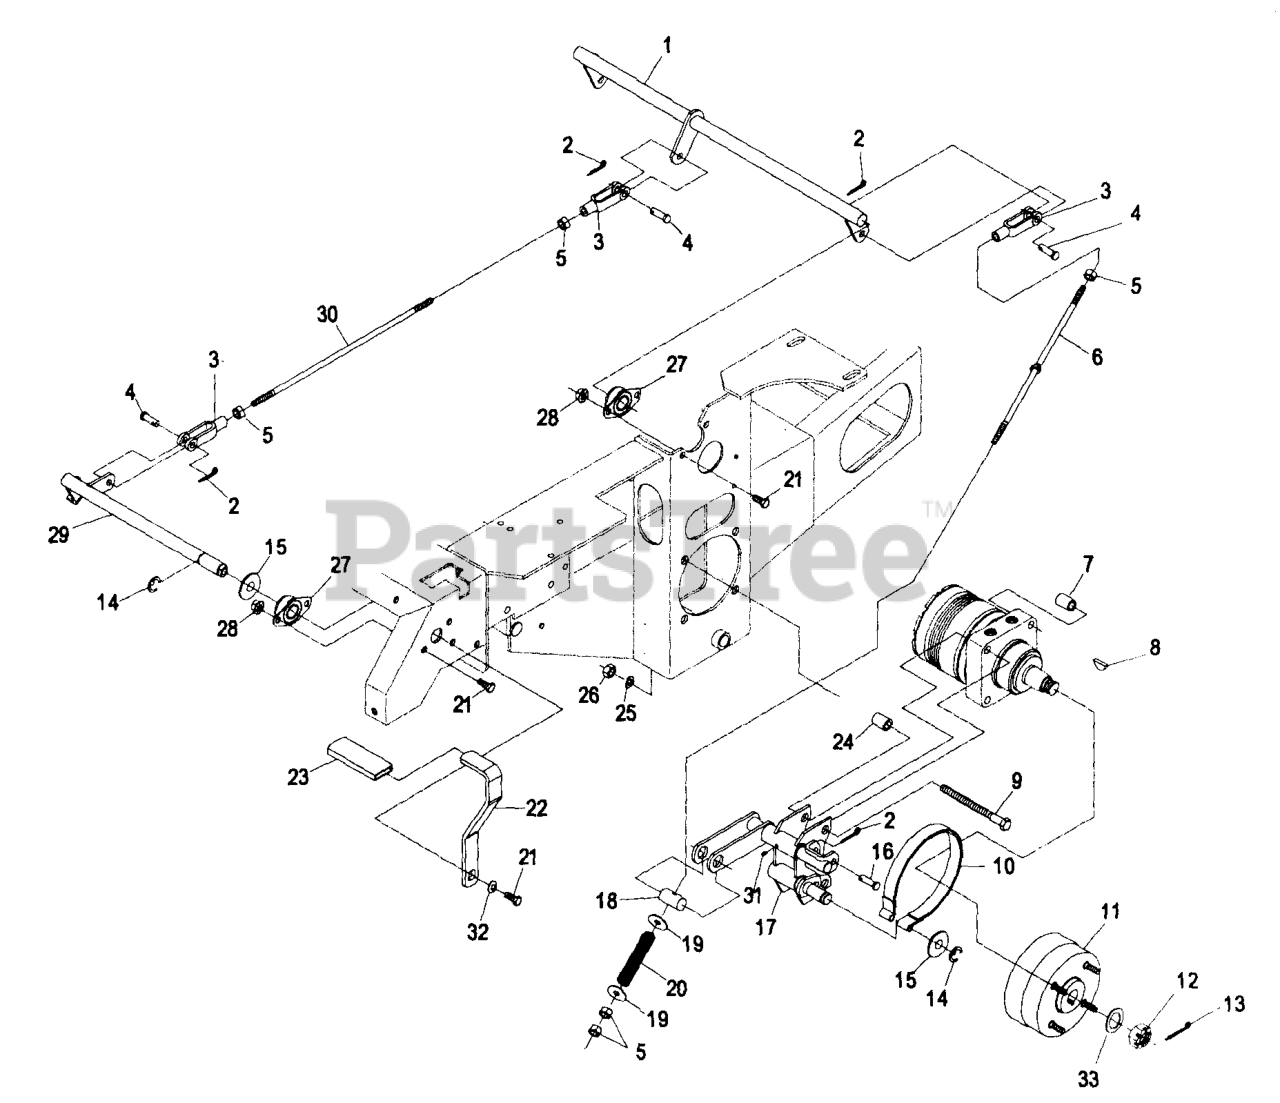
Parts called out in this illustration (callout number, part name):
1	CRANK-BRAKE, PARK
3	YOKE-LINKAGE, BRAKE
4	PIN-CLEVIS
6	ROD-BRAKE
7	SPACER-WHEEL
10	BAND,BRAKE
13	PIN-COTTER
16	PIN,CLEVIS 3/8X2
17	WLD,BRAKE BRACKET LH
18	PIN-TRUNION
20	SPRING-BRAKE
22	HANDLE-BRAKE, PARK
23	GRIP-LEVER
24	SPACER-WHEEL
27	BEARING-FLANGE, SIDE
30	LINKAGE-HANDLE, BRAKE
31	1481
33	WASHER-SPACER
